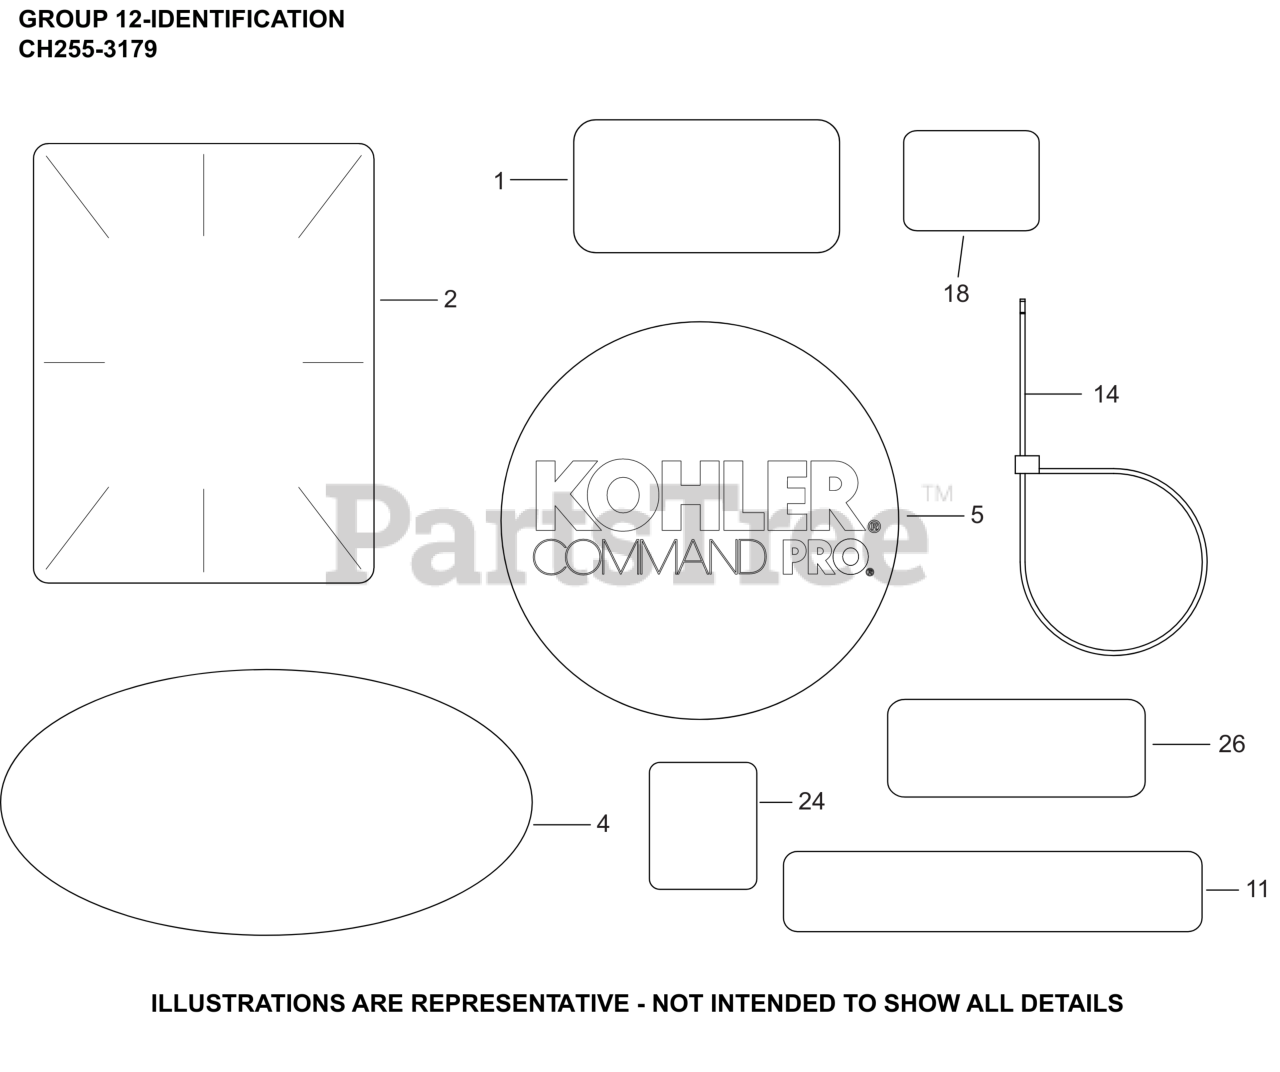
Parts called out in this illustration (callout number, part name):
1	LABEL, MAINTENANCE (CKY)
2	LABEL, CLEAR LAMINATION
4	DECAL, QUAD CLEAN
5	LABEL, RECOIL 75MM
11	LABEL, THROTTLE
18	DECAL, SUN
18	DECAL, SNOW
18	DECAL, ARROW
24	LABEL, CHOKE
26	LABEL, FUEL SECURE
